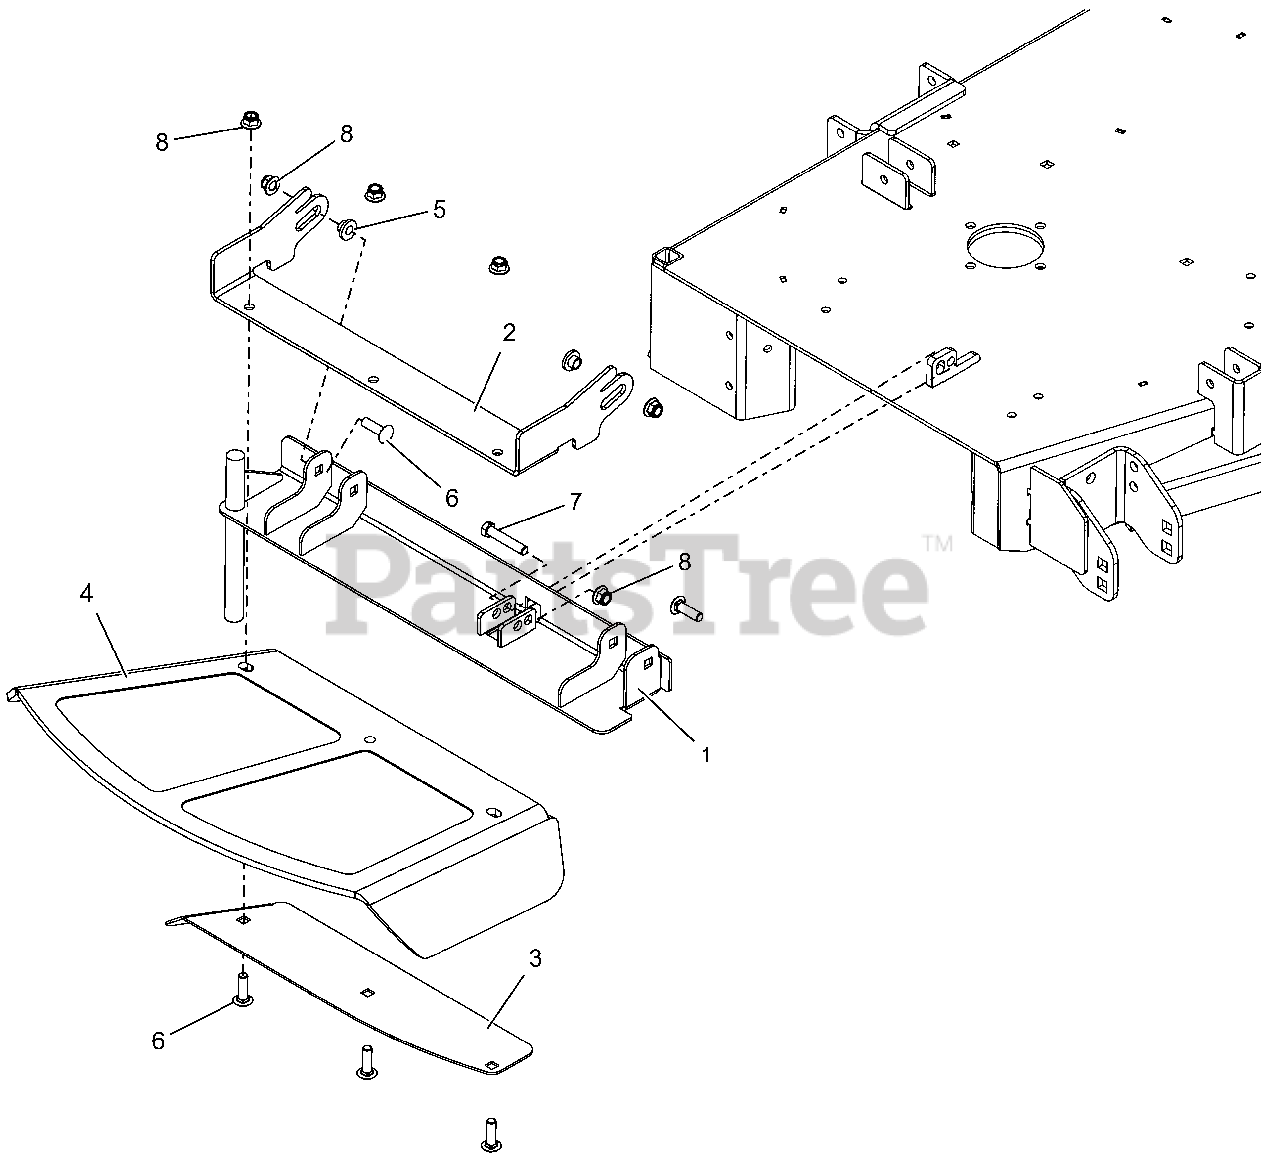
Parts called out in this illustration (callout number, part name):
1	48-60 DISCH CHT MTG WMT W/SAFE
2	48-60" CHUTE MTG BRKT - RED
3	48-60 DISCH CHUTE CLMP PLT-RED
4	CHUTE,48-60" FRMD RUBBER DISCH
5	BSHG-FLG .385X.500X.875X.406
6	@BLT-RHDSSQNK .38-16X1.25 G5YZ
7	@BLT-HEX .38-16X2.00 GR5 YWZC
8	@NUT-LK-NYL-FLG .38-16 YWZC
